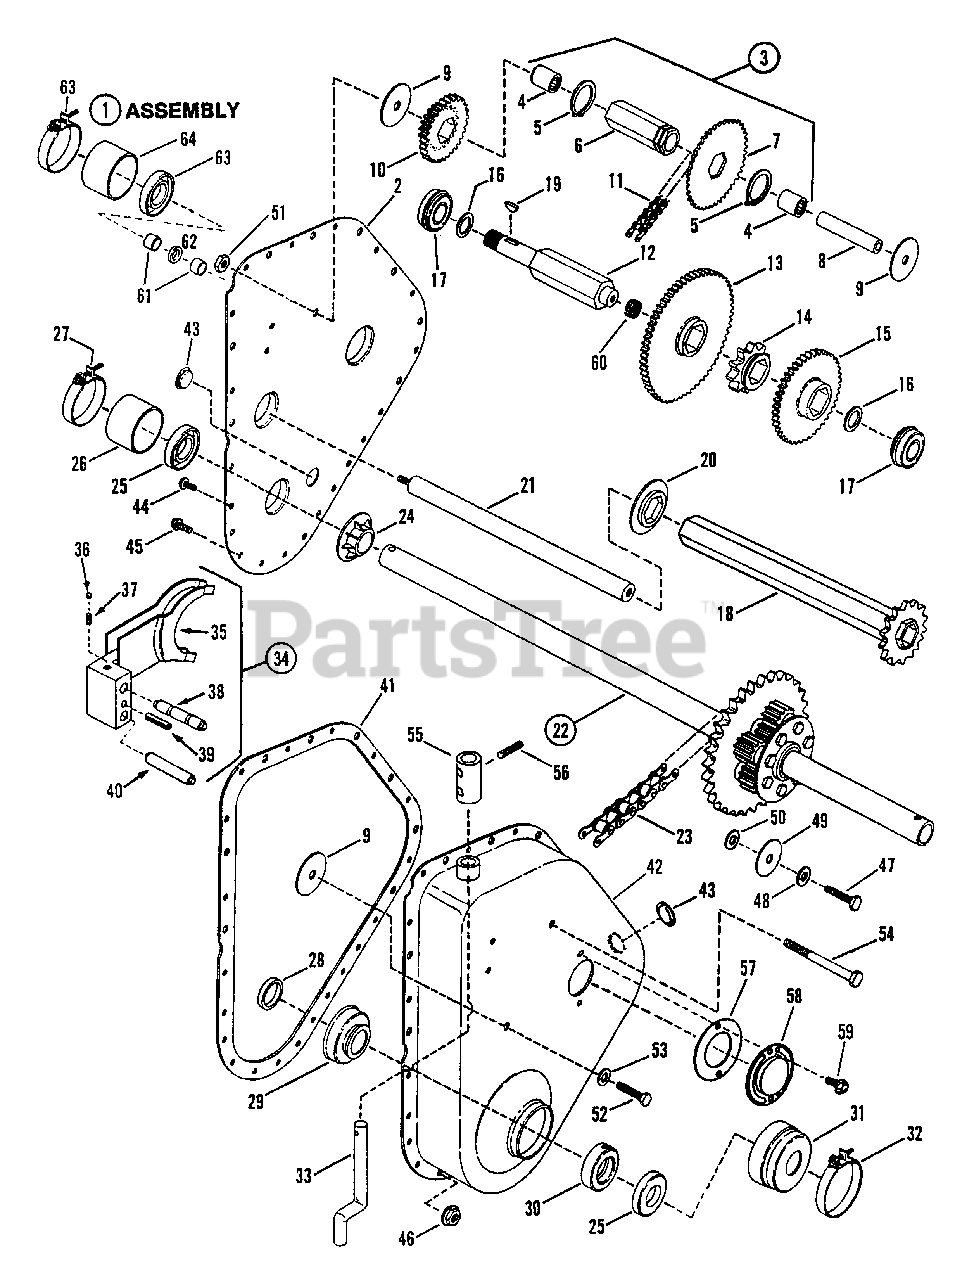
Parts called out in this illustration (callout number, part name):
1	ASSEMBLY, TRANSMISSION (NLA)
2	COVER, Transmission
3	ASSEMBLY, Hex Tube (Short)
4	BEARING, Needle
5	RING, Retaining
6	TUBE, Hex
7	SPROCKET, 46 Tooth (#35)
8	RACE, Bearing
9	THRUST WASHER
10	CLUSTER GEAR
11	CHAIN, 56 Pitch (#35)
12	SHAFT, Third Reduction 4.77" Long
12	SHAFT, Third Reduction (1985) 6.027" Long
13	GEAR, 67 Tooth, 12 Pitch Low Range
14	SPROCKET, 10 Tooth (#50)
15	GEAR, 47 Tooth, 12 Pitch High Range
16	SHIM WASHER
17	BEARING
18	ASSEMBLY, Drive Hex Tube
19	KEY, Woodruff (#9)
20	SPECIAL WASHER (Hex Insert)
21	SHAFT, Drive Tube Support
22	DIFFERENTIAL (NLA)
23	CHAIN, 42 Pitch (#50)
24	SPECIAL WASHER
25	OIL SEAL
26	CAP, Seal
27	CLAMP, 1-7/8" Hose
28	SPACER, Bearing
29	BEARING, Ball
30	COLLAR, Lock
31	CAP, Dust Seal
32	CLAMP, For 2.69" Hose
33	ROD, (HI-LO Range) Shift
34	ASSEMBLY, HI-LO Shifter
35	FORK, Shift
36	BALL, Detent
37	SPRING, Detent Ball
38	GUIDE-PIN, Detent
39	ROLL-PIN, 1/4 x 1-1/4"
40	GUIDE-PIN, Shift
41	GASKET, Cover to Case
42	ASSEMBLY, Transmission Case
43	PLUG, Oil Fill & Check
44	SCREW, 1/4-20 x 5/8" HWF Self Tap
45	BOLT, 1/4-20 x 1/2" HWF (2-Locating)
46	NUT, 1/4-20 Hex Flange Lock
47	SCREW, 5/16-24 X 3/4" Hex Head Cap
48	WASHER, 5/16 Split Lock
49	WASHER, 5/16" x 1-1/4" x 3/32" Flat
50	WASHER 5/16 SAE
51	NUT, 3/8-16 Hex Top Lock
52	SCREW, 3/8-16 x 3/4" Hex Head Cap, Grade 5
53	WASHER, 3/8 Split Lock
54	SCREW, 3/8-16 x 3-1/4" Hex Head Cap
55	COUPLING, Shift Lever
56	ROLL-PIN, 3/16 X 3/4"
58	COVER, Bearing
59	SCREW, 1/4-20 x 3/8" Hex Washer Self-Tap
60	RING, 5/8 Tolerance
61	SPACER, Brake Shaft
62	"O"-Ring
63	SEAL Oil
64	BOOT, Oil Seal
